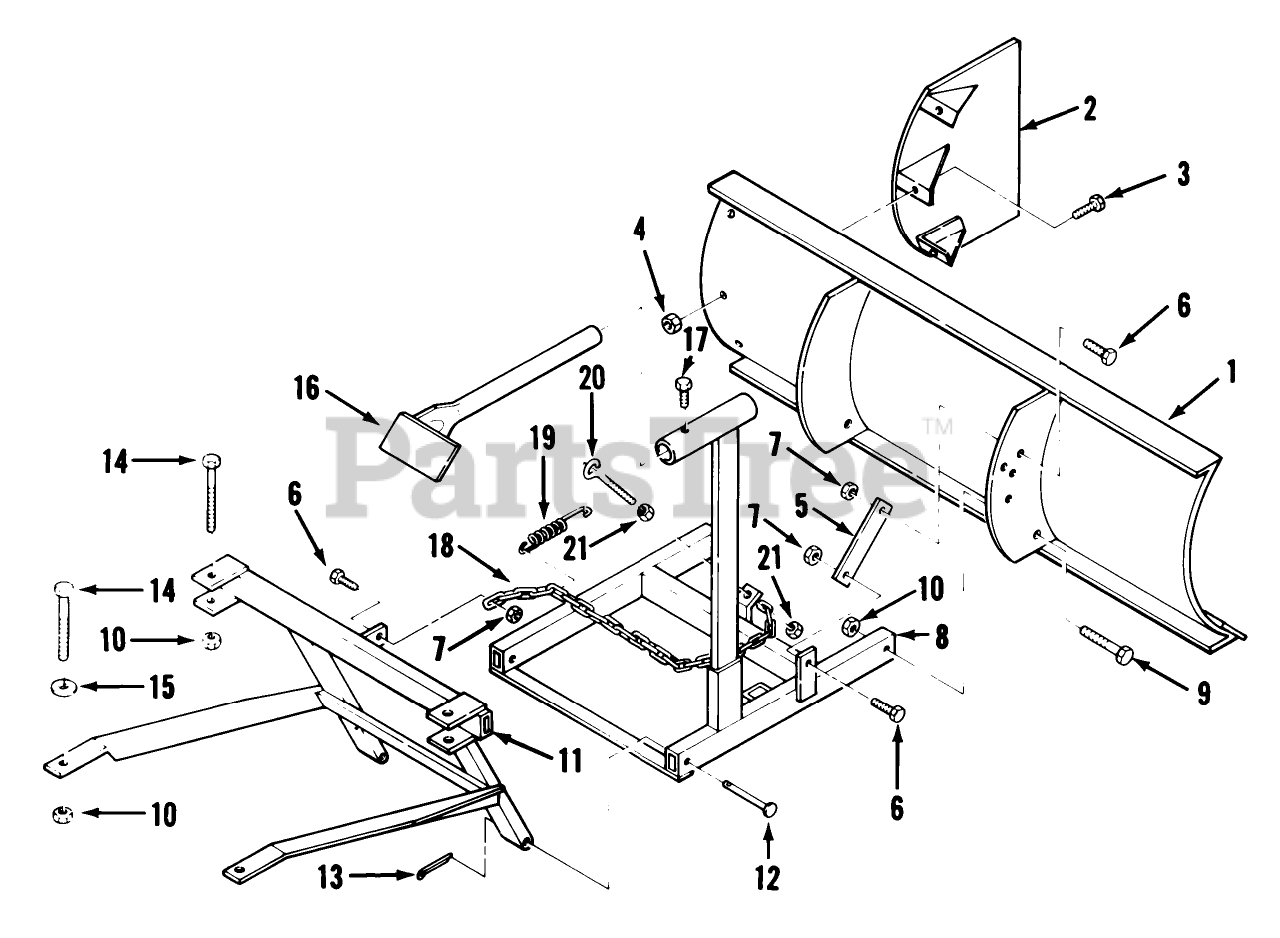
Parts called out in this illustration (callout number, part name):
1	Blade
2	End Plate
3	BOLT SCREW 10-32X1
4	Nut
5	ADJUSTING STRAP
6	Bolt
7	Nut
8	Front Frame
9	Bolt 1/2-13 X 2
10	Eslok Nut
11	Rear Frame
12	PIN CLEVIS
13	Hairpin Cotter
14	HEX HD CAP SCREW
15	Washer
16	Pedal
17	Set Screw
18	CHAIN
19	Spring
20	Eye Bolt
21	Flanged Nut
